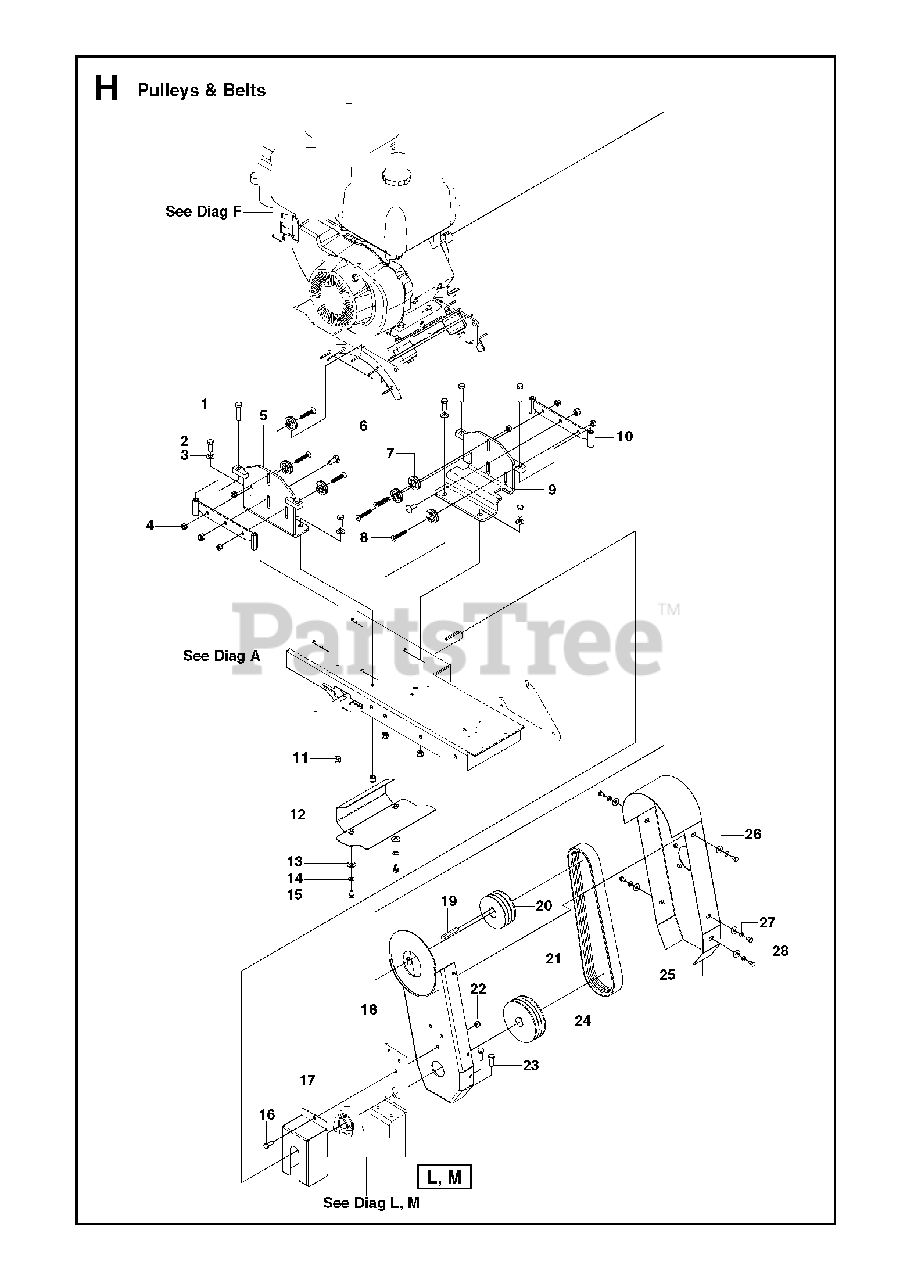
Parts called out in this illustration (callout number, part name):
3	WASHER
11	NUT
14	WASHER
15	SCREW
16	SCREW
22	NUT
28	HCS ¼-20 X ½ GR 5 ZD
